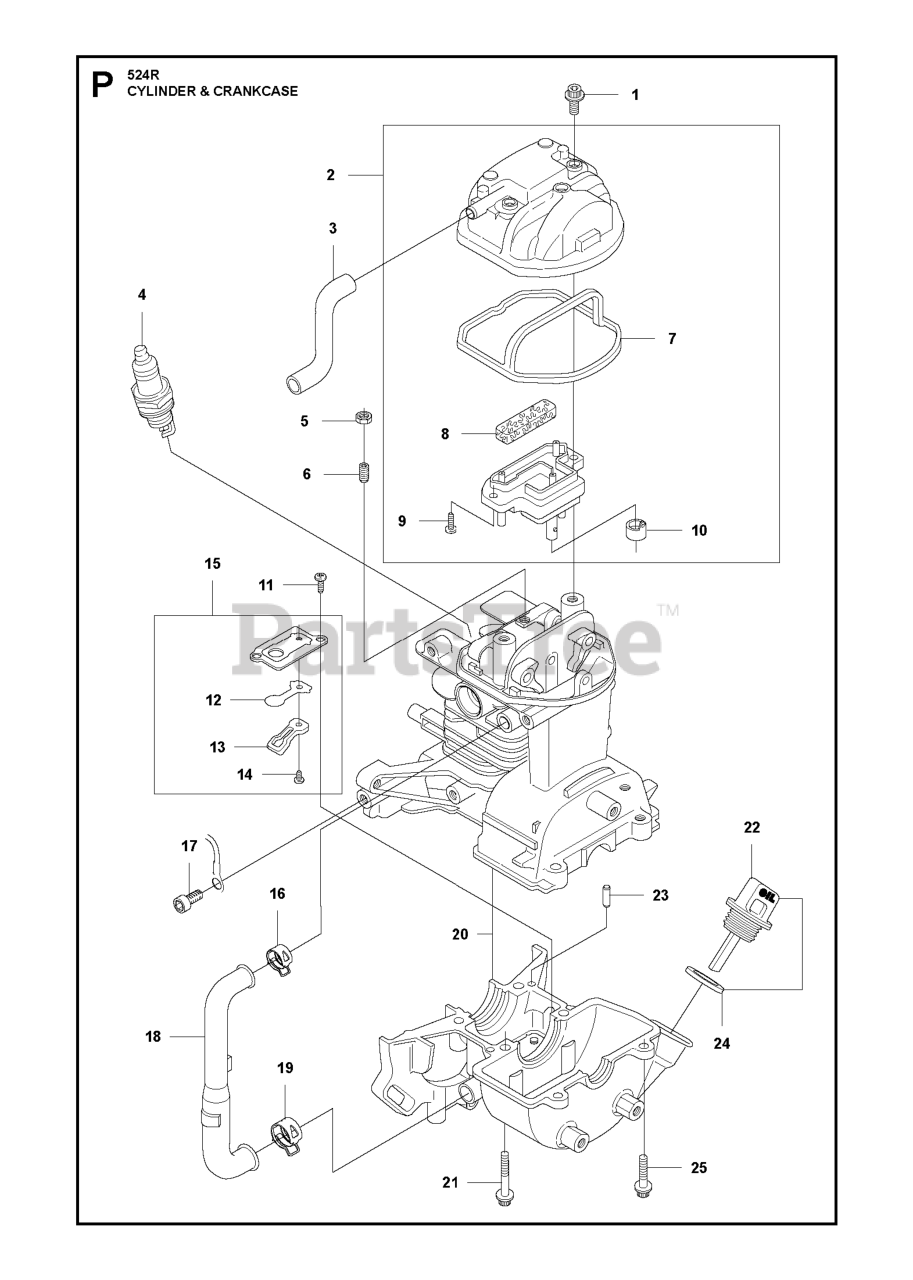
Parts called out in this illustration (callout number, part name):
4	SPARK PLUG
4	CMR6H NGK SPARK PLUG
4	CMR5H NGK SPARK PLUG
13	MOVEMENT LIMITER
17	SCREW MC6S 5X10
20	CRANKCASE / CYLINDER
